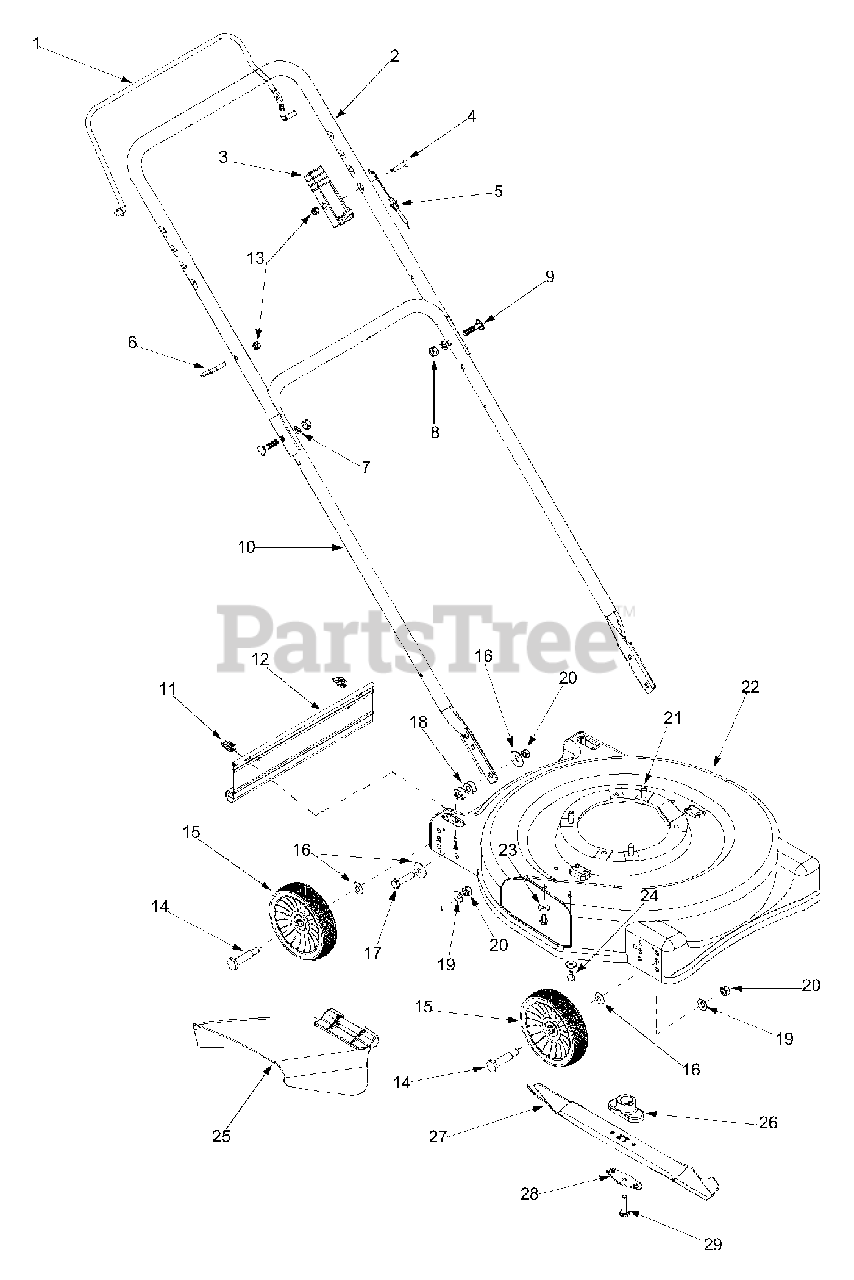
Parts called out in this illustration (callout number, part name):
4	Oval C-Sunk Screw
5	Control Cable
6	Rope Guide
7	Lock Washer 5/16"
8	Hex Nut 5/16-18
9	Carriage Bolt 5/16-18 x 1"
11	Hinge Clip
12	Rear Trail Shield
13	Hex Lock Nut
14	Axle Bolt
15	Wheel Assembly
16	Bell Washer .380 ID x .88"
17	Hex Bolt 3/8-24 x 1.5
18	Spacer .391" ID x .850" OD
19	Bell Washer .39 ID x 1.13 OD
20	Hex Nut 3/8-16
21	Hex Washer Screw 3/8-16 x 1"
24	Hex Washer Screw 1/4-20 x .5"
25	Chute Deflector Assembly
26	Blade Adapter
27	Blade
28	Bell Blade Support
29	Hex Bolt 3/8-24 x 1.5"
